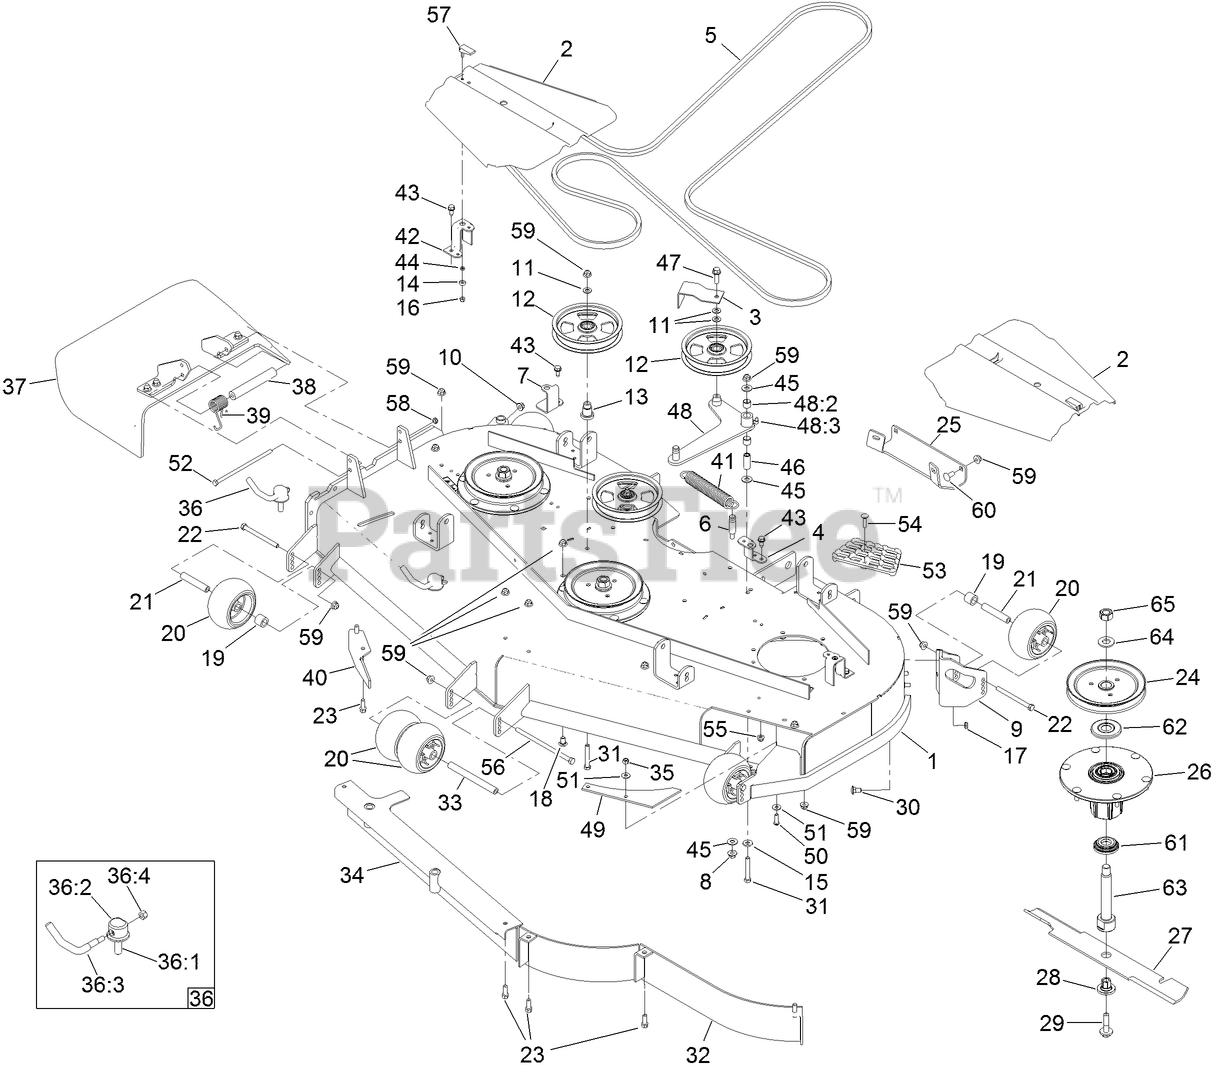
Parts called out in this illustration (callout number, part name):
1	DECK DECAL ASM
2	COVER-BELT
3	GUIDE-BELT
4	BRACKET-COVER, TALL
5	BELT-V
6	PIN-THREADED, SPRING ANCHOR
7	BRACKET-COVER
8	NUT-HF
9	MOUNT-WHEEL, LH
10	NUT-HHF, WHIZ
11	WASHER-FLAT
12	PULLEY-IDLER, FLAT
13	MOUNT-PULLEY
14	BUSHING-LATCH, SWELL
15	WASHER-BELLEVILLE
16	NUT-LOCK, HH
18	SCREW-CARR
19	TUBE-SPACER
20	ROLLER-SCALP, ANTI
21	TUBE-SPANNER
22	SCREW-HH
24	SHEAVE-DRIVE, BLADE
25	PLATE-SKID
26	SPINDLE ASM
28	BUSHING-HEX
29	SCREW-SEMS
30	SCREW-CARR
31	SCREW-HH
33	SPACER-WHEEL
34	BAFFLE ASM
35	NUT-LOCK, NI
36	LEVER ASM
36:1	SCREW-LOCK
36:2	CAP-LOCK
36:4	NUT-LOCK, NI
37	RUBBER DEFLECTOR ASM
38	SPACER
39	SPRING-TORSION
40	BAFFLE-DISCHARGE
41	SPRING-EXTENSION
42	BRACKET-COVER
43	SCREW-HWHTF
44	WASHER
45	WASHER-FLAT
46	BUSHING
47	SCREW-HHF
48	DECK IDLER ARM ASM
48:2	SLEEVE-BEARING
48:3	FITTING-GREASE, 90 DEG
49	PLATE-TURBO
50	SCREW-HSBH
51	WASHER-SPRING
52	SCREW-HH
53	STEP-DECK
54	SCREW-CARR
55	NUT-HF, NI
56	SCREW-HH
57	HANDLE-LATCH, SWELL
58	NUT-LOCK, NI
59	NUT-HF, NI
60	SCREW-CARR
61	GUARD-BOTTOM
62	GUARD-BEARING, TOP
63	SHAFT-SPINDLE
64	WASHER
65	NUT-HEX
